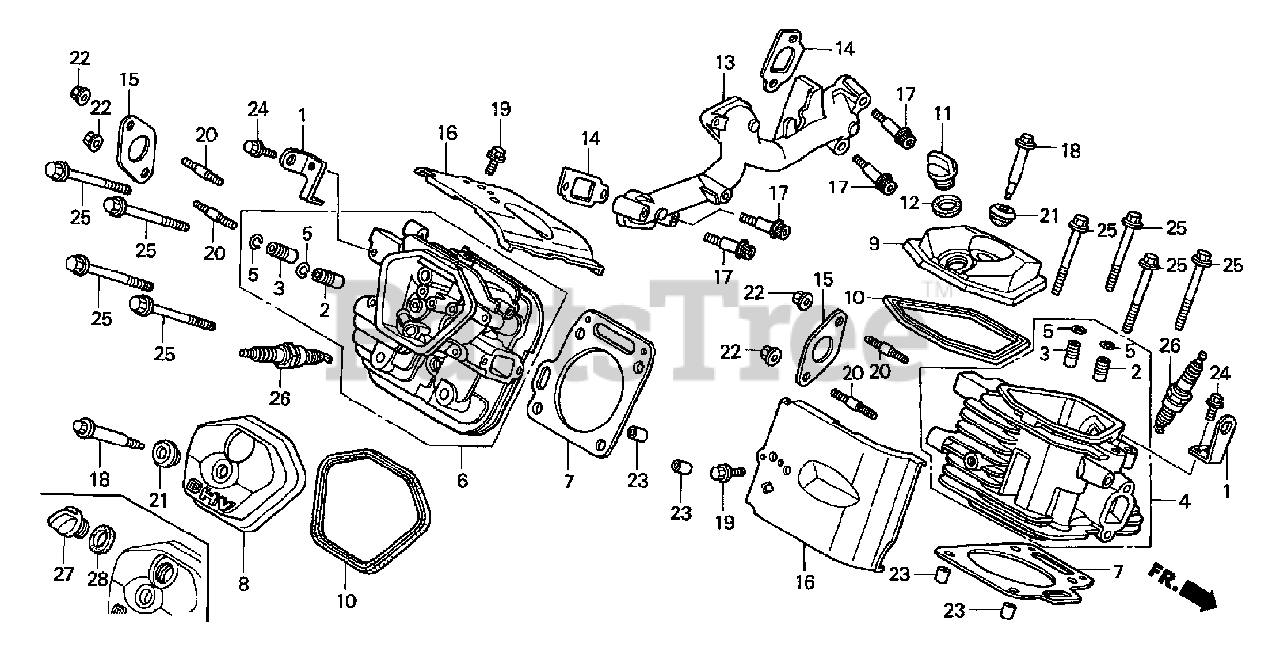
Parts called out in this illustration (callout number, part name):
1	Hanger, Engine
2	Guide, Valve (OS)
3	Guide, Ex. Valve (OS)
4	Cylinder Head (#1)
5	Clip, Valve Guide
6	Cylinder Head (#2)
7	Gasket, Cylinder Head
8	Cover, Head
9	Cover, Head Filler
10	Gasket, Cylinder Head Cover
11	Cap, Oil Filler
12	Gasket, Oil Filler Cap
13	Manifold, In
14	Gasket, In. Manifold
15	Gasket, Ex. Pipe
16	Shroud, Head
17	Bolt, Socket (8x45)
18	Bolt, Head Cover
19	Bolt, Flange (6x14)
20	Bolt, Stud (8x22)
21	Washer, Head Cover
22	Nut, Flange (8mm)
23	Pin A, Dowel (12x20)
24	Bolt, Flange (8x20)
25	Bolt, Flange (10x80)
26	Spark Plug (BPR2ES) (NGK)
